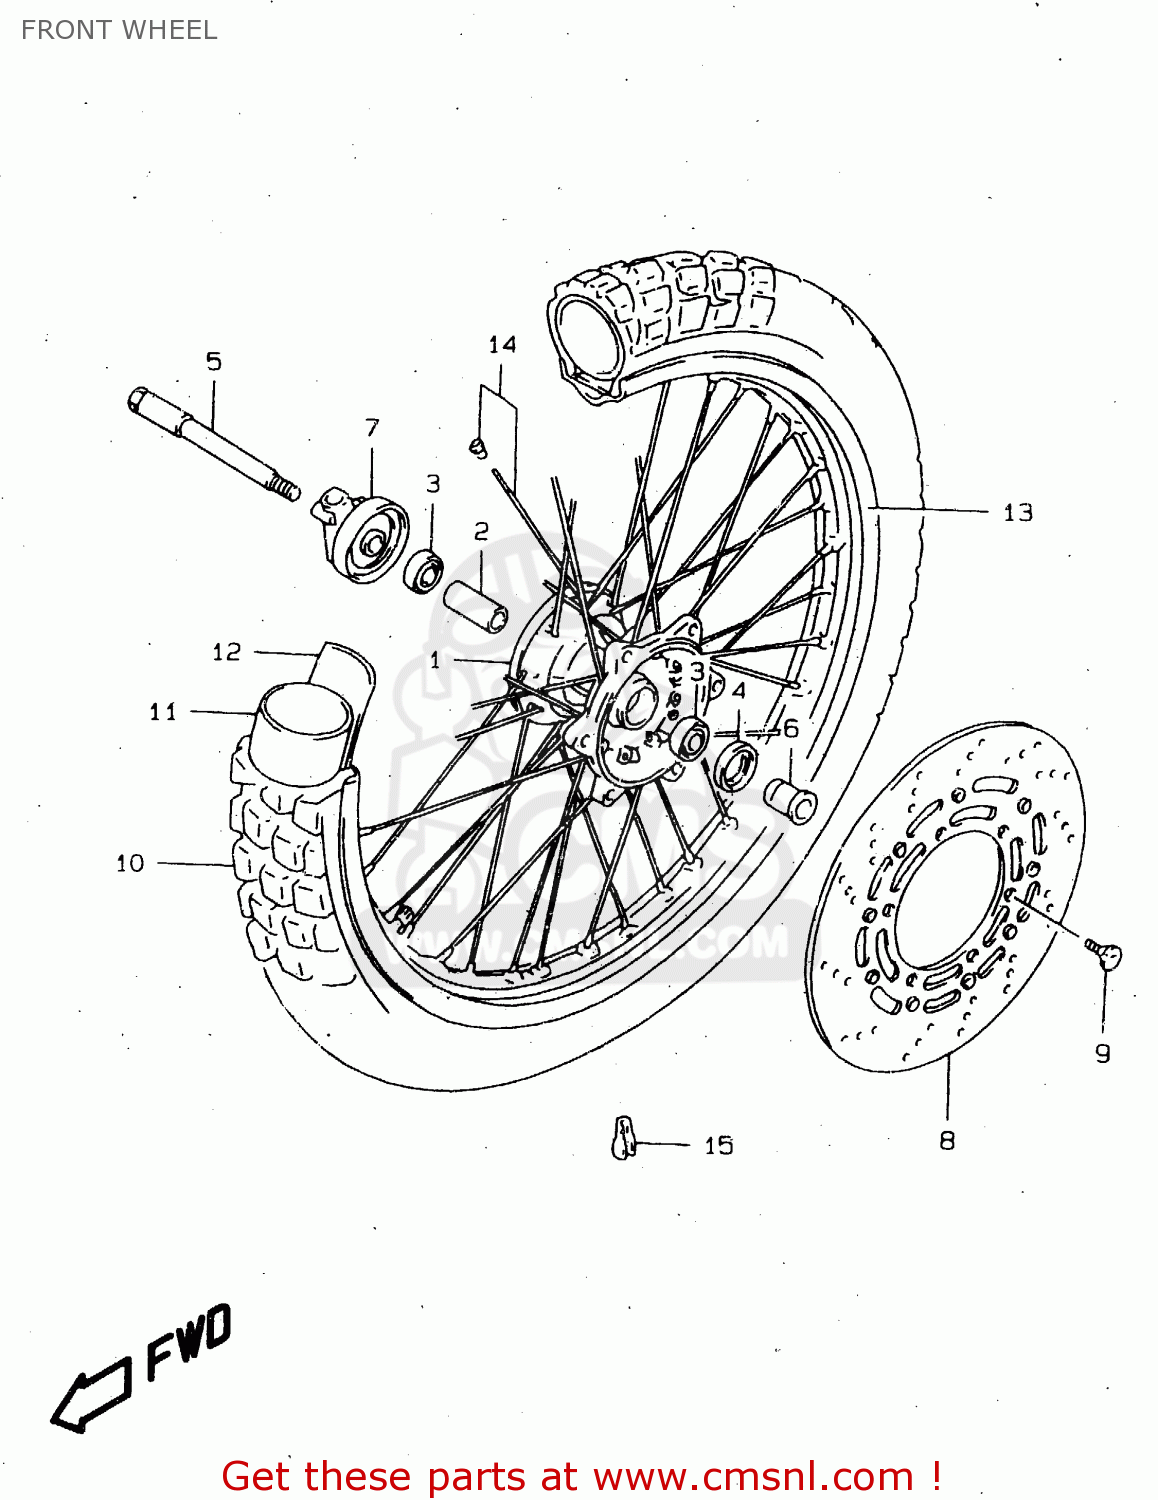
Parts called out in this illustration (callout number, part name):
1	HUB,FR WHEEL
2	SPACER,FR HUB BEARING
3	BEARING
4	SEAL,OIL(23X35X6)
5	AXLE,FR
6	SPACER,FR AXLE,L
7	BOX ASSY,SPEEDOMETER GEAR
8	DISC,FR BRAKE
9	BOLT,BRAKE DISC
10	TIRE,FR(90/90-21 54S)
11	TUBE ASSEMBLY,WHEEL,INNER
12	PROTECTOR,WHEEL,INNER
13	RIM,FR WHEEL(21X1.85)
14	SPOKE SET,FR WHEEL
15	BALANCER,WHEEL
